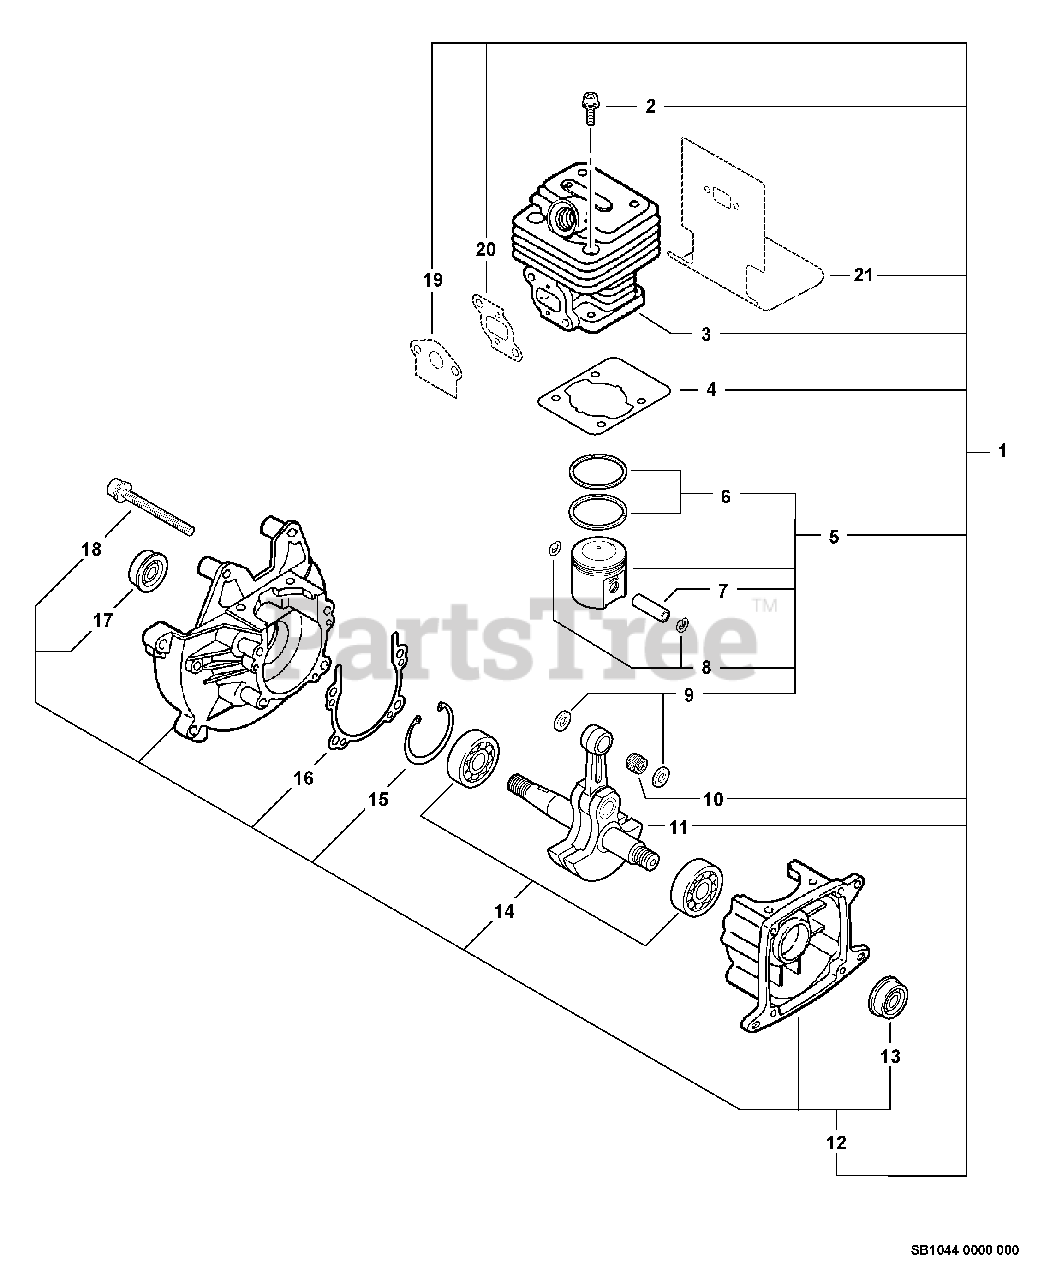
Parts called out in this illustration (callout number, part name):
1	SHORT BLOCK
2	BOLT 5×22
3	CYLINDER
4	GASKET, CYLINDER
5	PISTON KIT
6	RING, PISTON
7	PIN, PISTON
8	RING, SNAP
9	WASHER, THRUST
10	BEARING, NEEDLE 8
11	CRANKSHAFT ASSY
12	CRANKCASE KIT
13	SEAL, OIL 12
14	BEARING, BALL 6001
15	RING, SNAP 28
16	GASKET, CRANKCASE
17	SEAL, OIL 12
18	BOLT 5×25
19	GASKET, INTAKE
20	GASKET, INTAKE
21	SHIELD, EXHAUST
